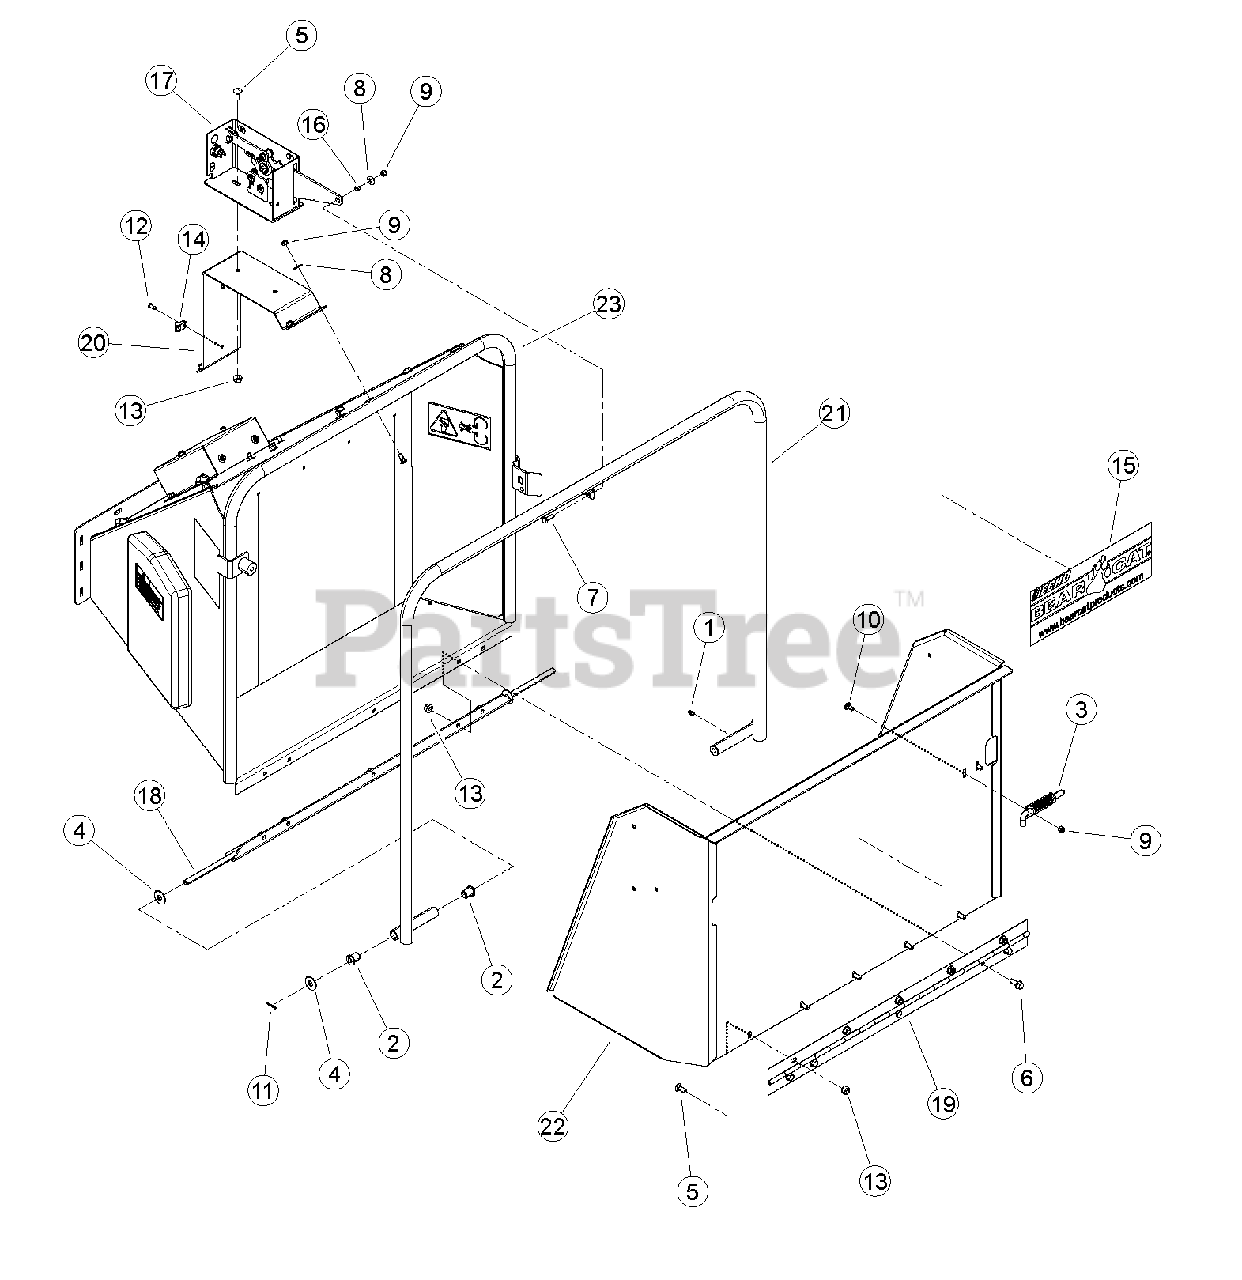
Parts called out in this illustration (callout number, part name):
1	FITTING, 1/4 SELF-TAP GREASE
2	BUSHING, 1/2 X 1 FLANGE LUBE
3	LATCH, RH HINGE
4	WASHER, 1/2" FLAT ZP
5	BOLT, 3/8 X 1" GR5 CRG NC ZP
6	BOLT, 3/8 X 1 FLANGE NC
7	BOLT, 5/16 X 1" GR5 HHCS NC ZP
8	WASHER, 5/16" FLAT ZP
9	NUT, 5/16" NE NYLOCK ZP
10	BOLT, 5/16 X 3/4 GR5 CRG NC ZP
11	PIN, 1/8 X 1.00 ZP COTTER
12	RIVET, AL BLIND 1/4 X 3/4 DOME HEAD
13	NUT, 3/8-16 NYLOCK FLANGE
14	CLAMP, CABLE MOUNT
15	DECAL, BEARCAT WEB
16	SPACER, IDLER PIVOT
17	ASSEMBLY, SWITCH BOX
18	WELDMENT, CONTROL PIVOT
19	HINGE, EXTENSION TRAY
20	MOUNT, SWITCH BOX
21	WELDMENT, CONTROL ARM
22	WELDMENT, EXTENSION TRAY W/O TABS
23	WELDMENT, CHIPPER CHUTE
